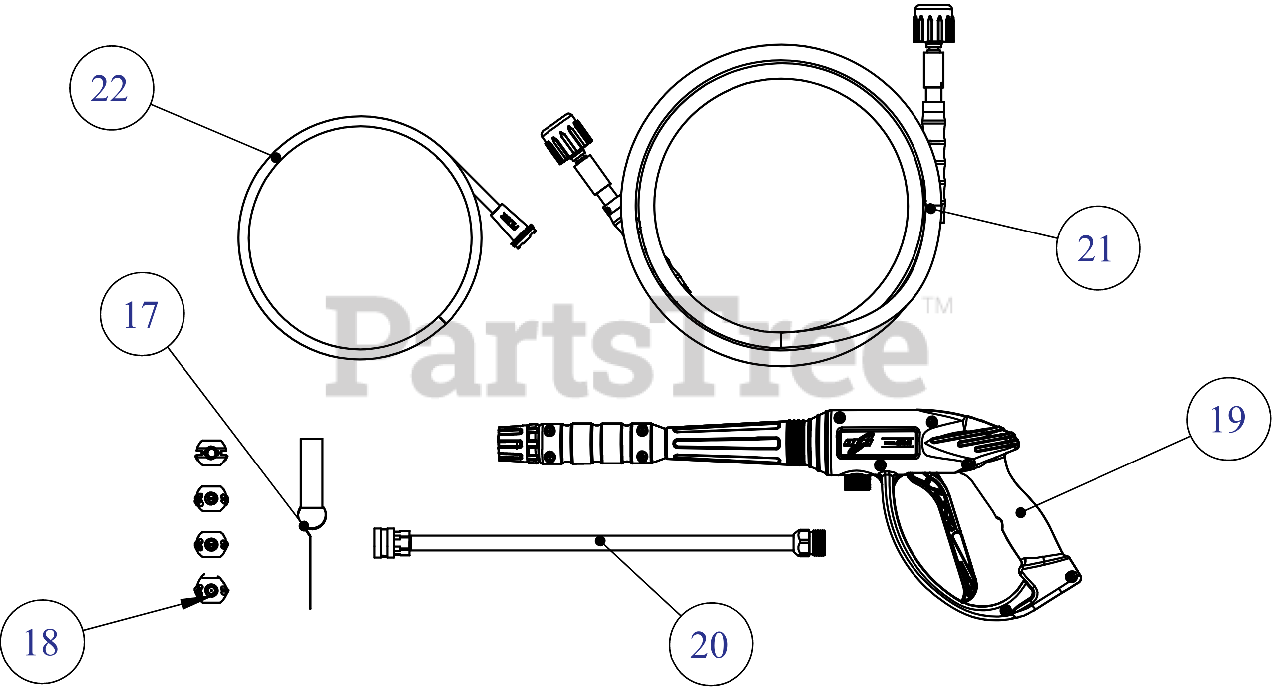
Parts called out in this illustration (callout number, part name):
17	TOOL-NOZZLE CLEANING
18	4 PIECE NOZZLE SET
19	SPRAY GUN FRONT ENTRY
20	WAND-SPRAY GUN 16"
21	SPRAY GUN HOSE 25'
22	HOSE-SOAP W/FILTER
